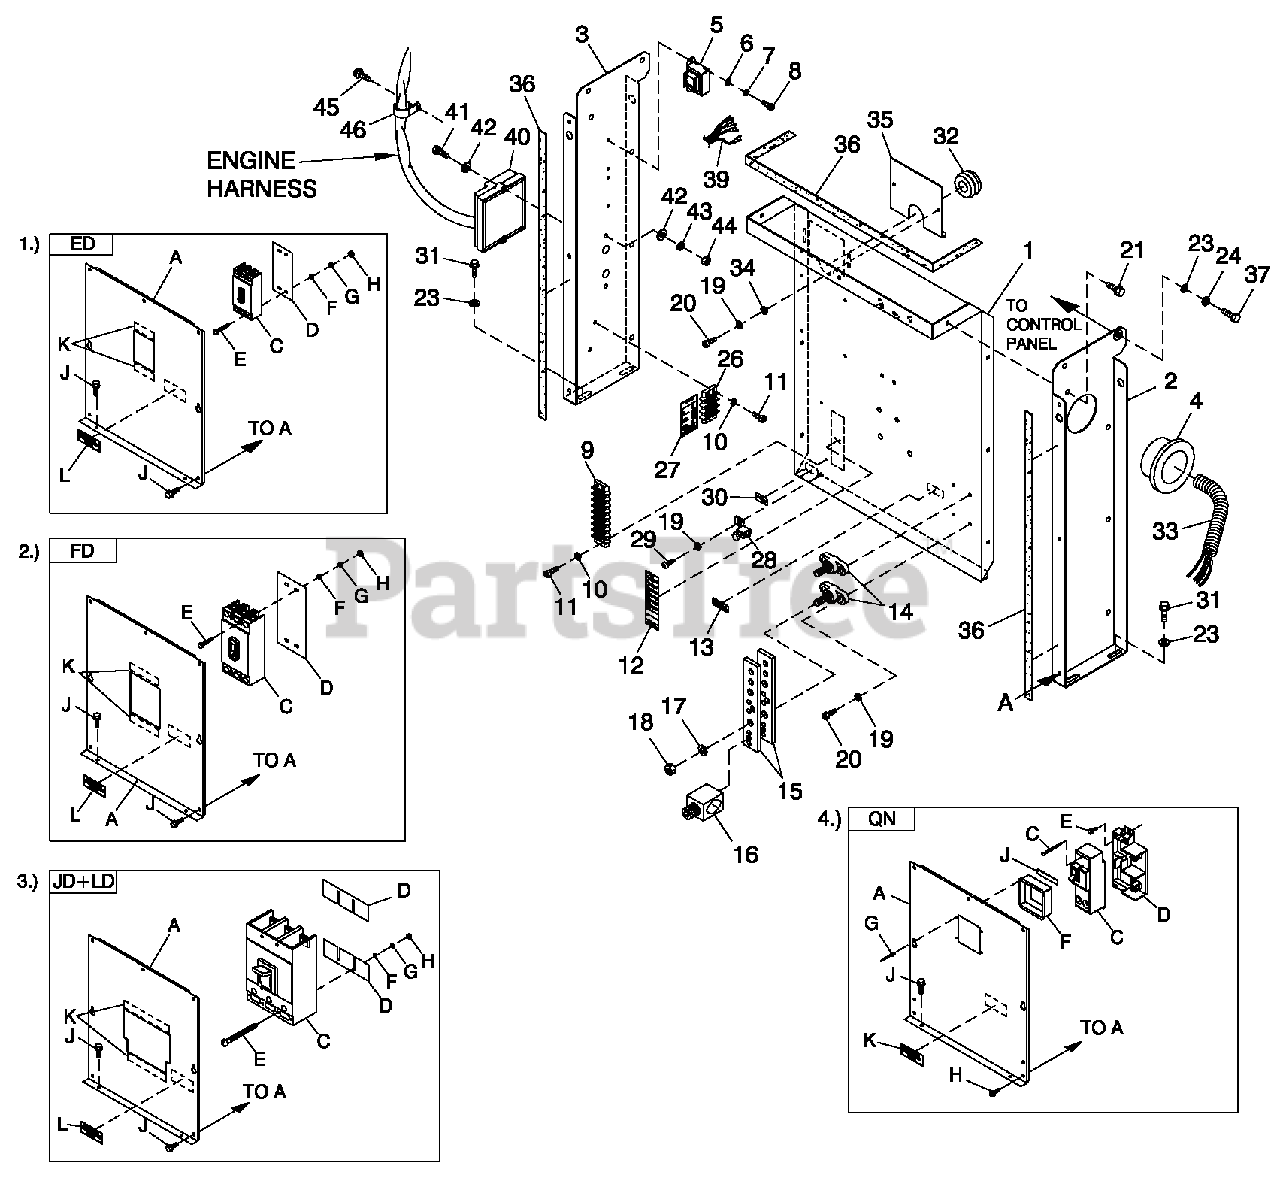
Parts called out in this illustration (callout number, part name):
1	PAN CBCONN BOX
1	UL CIRCUIT BREAKER(ED)
2	STAND RH CONTROL
2	UL CIRCUIT BREAKER (FD)
3	STAND LH CONTROL
3	UL CIRCUIT BREAKER (JD+LD)
4	BUSHING SNAP SB-2.5-31
4	UL CIRCUIT BREAKER (QN)
5	XFMR DUAL 120V/16V (FOR 120/240V & 277/480V UNITS)
6	WASHERFLAT M4
7	WASHERLOCK #8-M4
8	SCREW PHTT M4-0.7 X 10ZYC
9	BLOCKTE RM 20A8 X 6 X1100V
10	WASHERLOCK #6
11	SCREW PHTT #6-32 X 1/2Z YC
12	DECAL UTL SENSE/CUST CONN
13	DECAL UTRAL
14	JUNCTION BLOCK 3/8-16
15	BUS BAR NEUTRAL BLOCK 390
16	LUG SLDLSS 600/250-1/0 X 1/4-28
17	WASHERLOCK 3/8
18	NUT HEX 3/8-16 STEEL
19	WASHERLOCK M5
20	SCREW PHTT M5-0.8 X16ZYC
21	SCREW THFM6-1X 16N WAZ/JS
23	WASHERFLAT 1/4-M6ZINC
24	WASHERLOCK M6-1/4
26	BLOCKTE RM 20A6 X 3 X1100V
27	DECAL CUST CONN 120V UTILITY
28	LUG SLDLSS#6-14X13/64 CU
29	SCREW HHTT #10-32 X 3 /8C Z
30	DECAL GROUND LUG
31	SCREW HHTT M6-1.0 X16ZYC
32	GROMMET 1.25X .25 X .75
33	CONDUIT FLEX 2.0' ID (36" LG)
34	WASHERFLAT M5
35	PLATE WIRE SNGLGALV
36	TAPE ELEC 1/2 FOAM (AS REQ'Q
37	SCREW HHC M6-1.0X 16G8.8
39	HARNESS, TRANSFORMER ADAPTER
40	ASSY ENCLOSURE PCB 4.2L IGN MD
41	SCREW PPHM #10/32X2
42	WASHERFLAT # 1 0ZINC
43	WASHERLOCK #10
44	NUT HEX#10-32 STEEL
45	SCREW THF M6-1 X 1 6 N WAZ/JS
46	CLAMP VINYL 1.06 X .406 Z
47	SEALWEATHER.45' DIA
A	COVERED CB SHORT STND
C	CB0050A3P 480V S ED4 LL
D	INSULATOR CBS (ED-3 P)
E	SCREW RHM #10-32X4-1/2
F	WASHERFLAT # 1 0ZINC
G	WASHERLOCK #10
H	NUT HEX#10-32 STEEL
J	SCREW THF M 6-1 X 16 NWAZ/JS
K	TAPE ELEC 1/2 FOAM (AS REQ'D)
L	DECAL CUSTOMER CONNECT INSIDE
A	COVERCBCONN BOX
C	CB0150A3P 600VS FD6LL
D	INSULATOR CB FD FRAME 30ML
E	SCREW SHC1/4-20X 4.5 G8.8NZ
F	WASHERFLAT 1/4-M6ZINC
G	WASHERI OCK MR. 1/4
H	NUT HEX 1/4-20STEEL
J	SCREW THF M6-1 X 1 6 NWAZ/JS
L	DECAL CUSTOMERCONNECT INSIDE
A	COVER JD/LDCB SHRT STAND
C	CB 0300A3P600V SJD6 LL
D	INSULATOR CIRCUIT BR. JD/LD
E	SCREW RHM 1/4-20 X 3
F	WASHER FLAT 1/4-M6 ZINC
G	WASHER LOCK M6-1/4
A	COVER QN FRMCB
C	CB0150A2P240V SQN2 LL
D	BASE, QNCIRCUIT BREAKER
E	SCREW HHTT M 5 -0 .8X 1 0B P
F	COVER QNCBDISH
G	RIVET POP .125 X .275 SS
H	SCREW THF M 6-1X16 N WAZ/JS
J	TAPE ELEC 1/2 FOAM (AS REQ'D)
K	DECAL CUSTOMERCONNECT INSIDE
